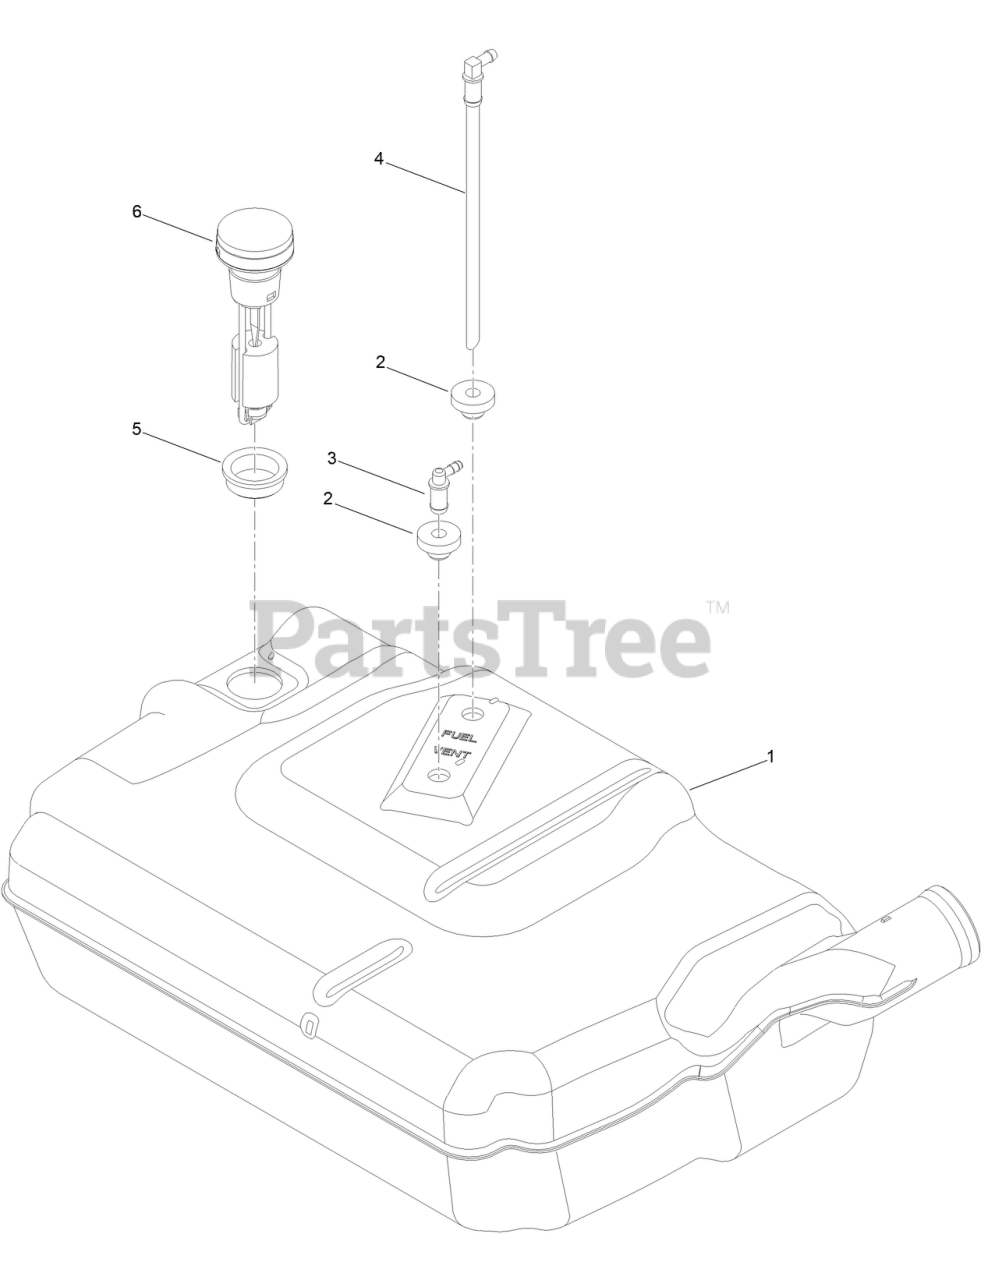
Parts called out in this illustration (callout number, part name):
1	TANK-FUEL
2	BUSHING
3	FITTING-ELBOW 90
4	FITTING-PICKUP, FUEL
5	GROMMET-FUEL
6	REMOTE GAUGE ASM
